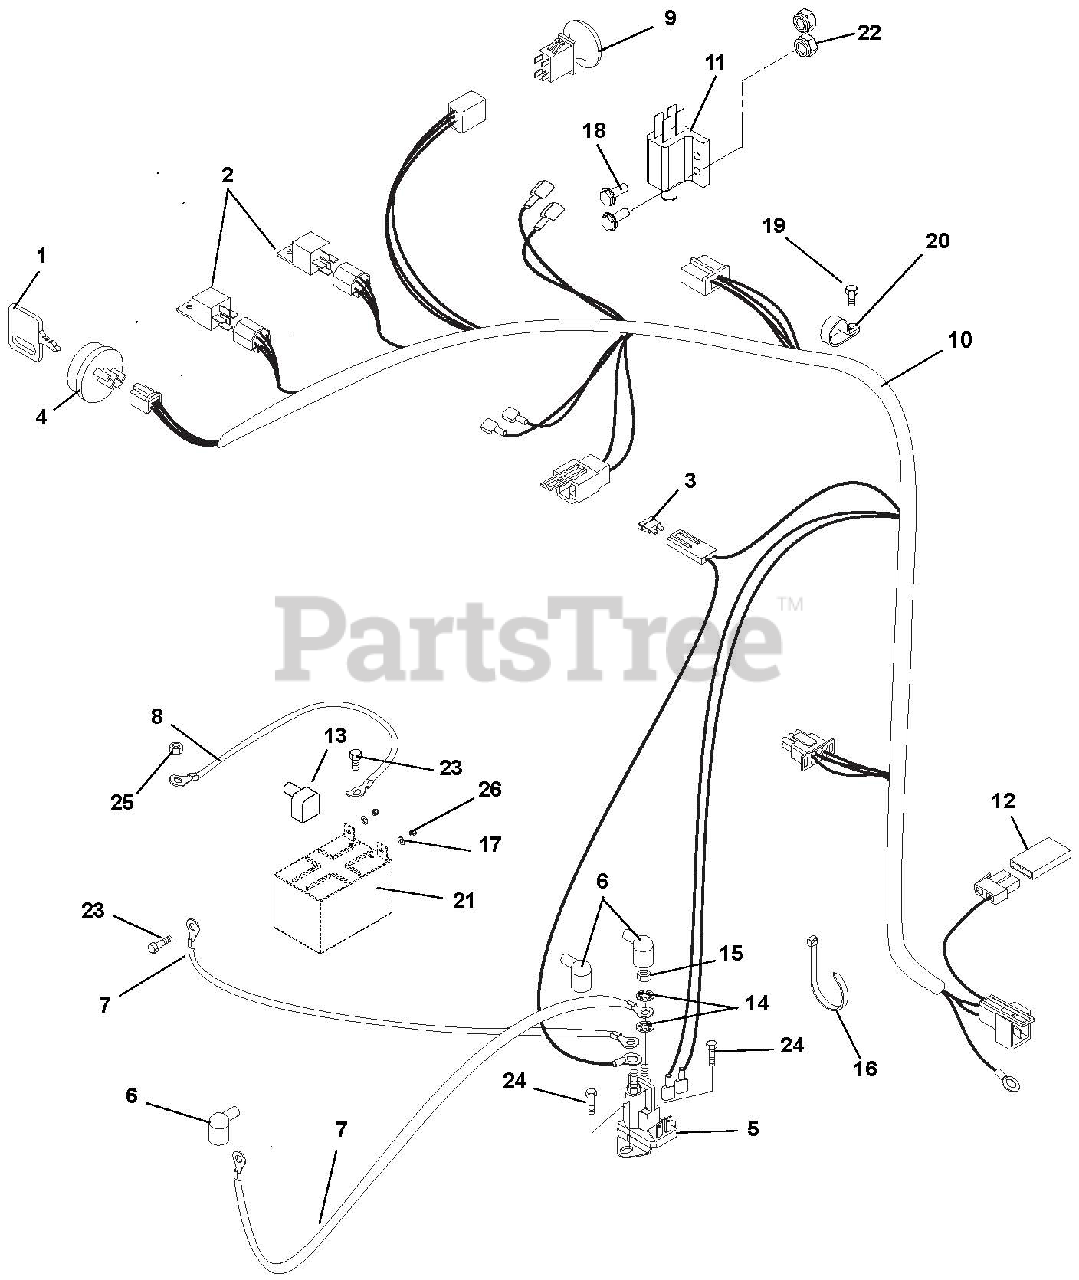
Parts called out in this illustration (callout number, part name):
1	Key with Cap
2	Relay
3	Fuse, 30 AMP
4	Key Switch
5	Solenoid,Starter
6	Boot, Eyelet Terminal
7	Starter Cable
8	Cable, Ground .25 x 13.00 x .31
9	Switch, Clutch With Retainer
11	Switch, Double Pole N.O. / N.O.
12	Diode, Connector Shell
13	Insulator
14	Washer, Locking .31
15	Nut, Jam .31-24
16	Cable Tie
17	Washer, FL-STL .281x.62x.065
18	Screw, Hex Washer Head Machine 10-24 x .75
19	Screw, Tapping Hex Washer Head Thread Rolling .38-16 x .50
20	Clamp, Cushioned Steel .75
21	Battery, 12V-12A-190CCA
22	NUT, LOCKING NYLON 10-24 WITH INSERT
23	Bolt-Hex .25-20x.75 GR5 YWZC
24	Screw-Tap .25-20x.37 HWH YWZTR
25	Nut-Lock Top FLG .25-20 YWZC
26	Nut - KEPS .25-.20
27	Decal, U1 Battery Replacement
